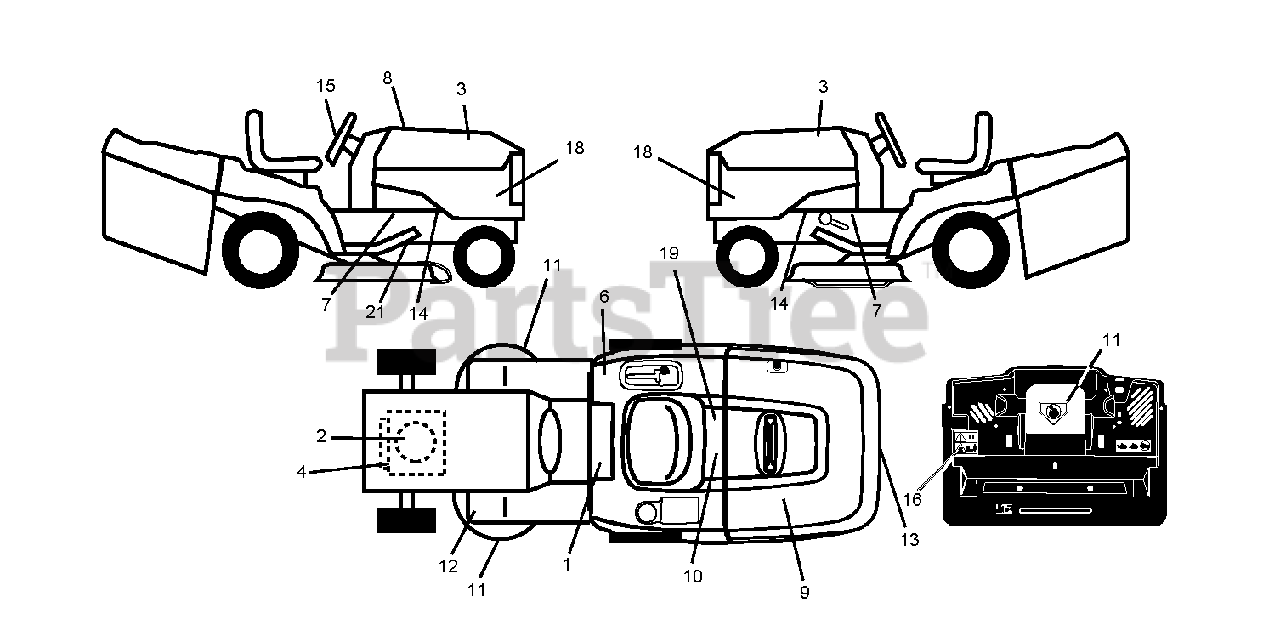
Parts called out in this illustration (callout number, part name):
10	DECAL BTRY SYMBOLS
11	DECAL.INTERNATIONL.CUTFINGER
19	DECAL PARK BRAKE
